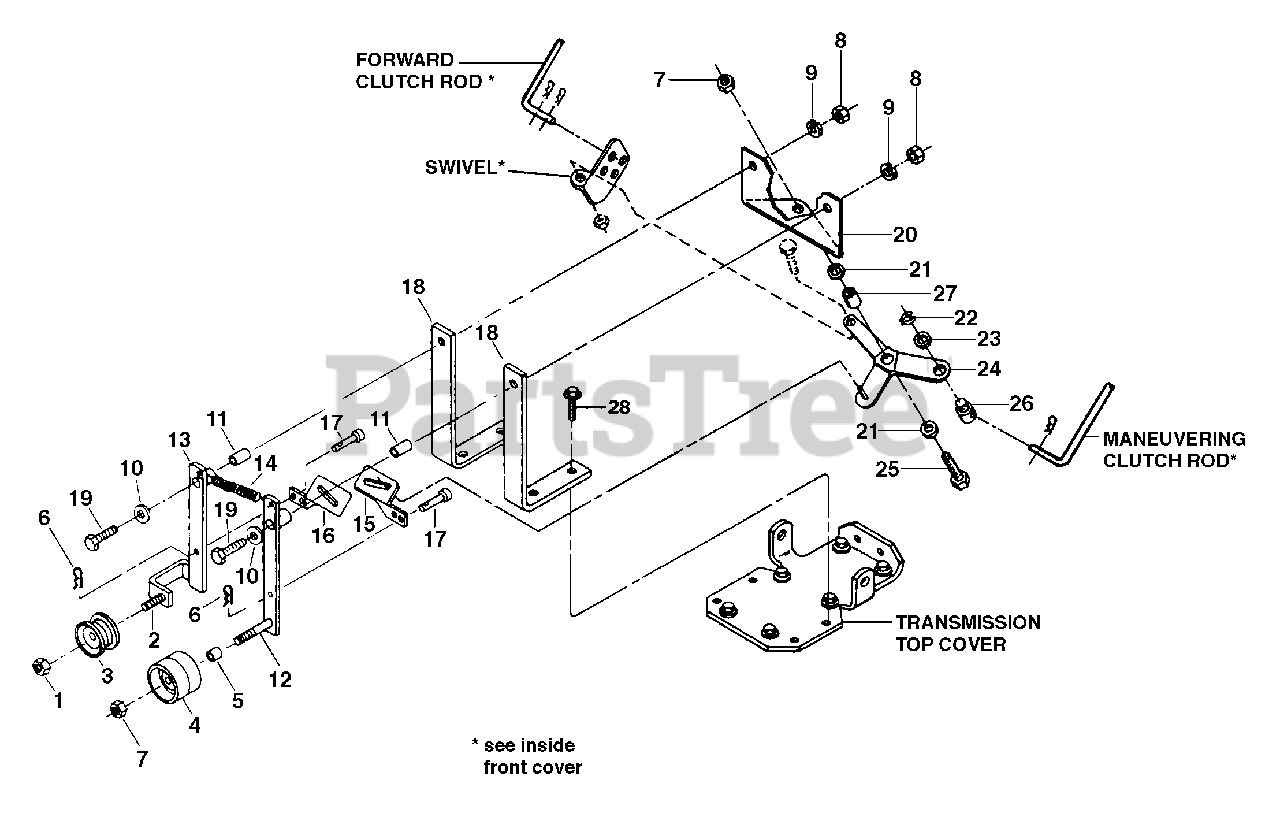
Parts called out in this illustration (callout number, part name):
1	Locknut, hex, 3/8-16
2	Screw, hex hd., 3/8-16 x 1-1/4 Grade 5
3	Pulley, idler, reverse
4	Pulley, idler, forward
5	Spacer
6	Hairpin cotter
7	Locknut, hex, 3/8-16
8	Nut, hex, 5/16-18
9	Lockwasher, 5/16
10	Washer, plain, 5/16
11	Pivot, bushing
12	Idler Arm, left, forward tiller direction
13	Idler Arm, right, reverse tiller direction
14	Spring
15	Forward Link
16	Reverse Link
17	Pin
18	Mounting Bar
19	Screw, hex hd., 5/16-18 x 2-1/4", Grade 5
20	Shifting base
21	Spacer, bushing
22	Klip Ring
23	Washer, pivot
24	Bellcrank
25	Screw, hex hd., 3/8-16 x 1-1/4
26	Pivot
27	Bushing, bellcrank
28	Screw, flanged hex hd., 5/16-18 x 1
